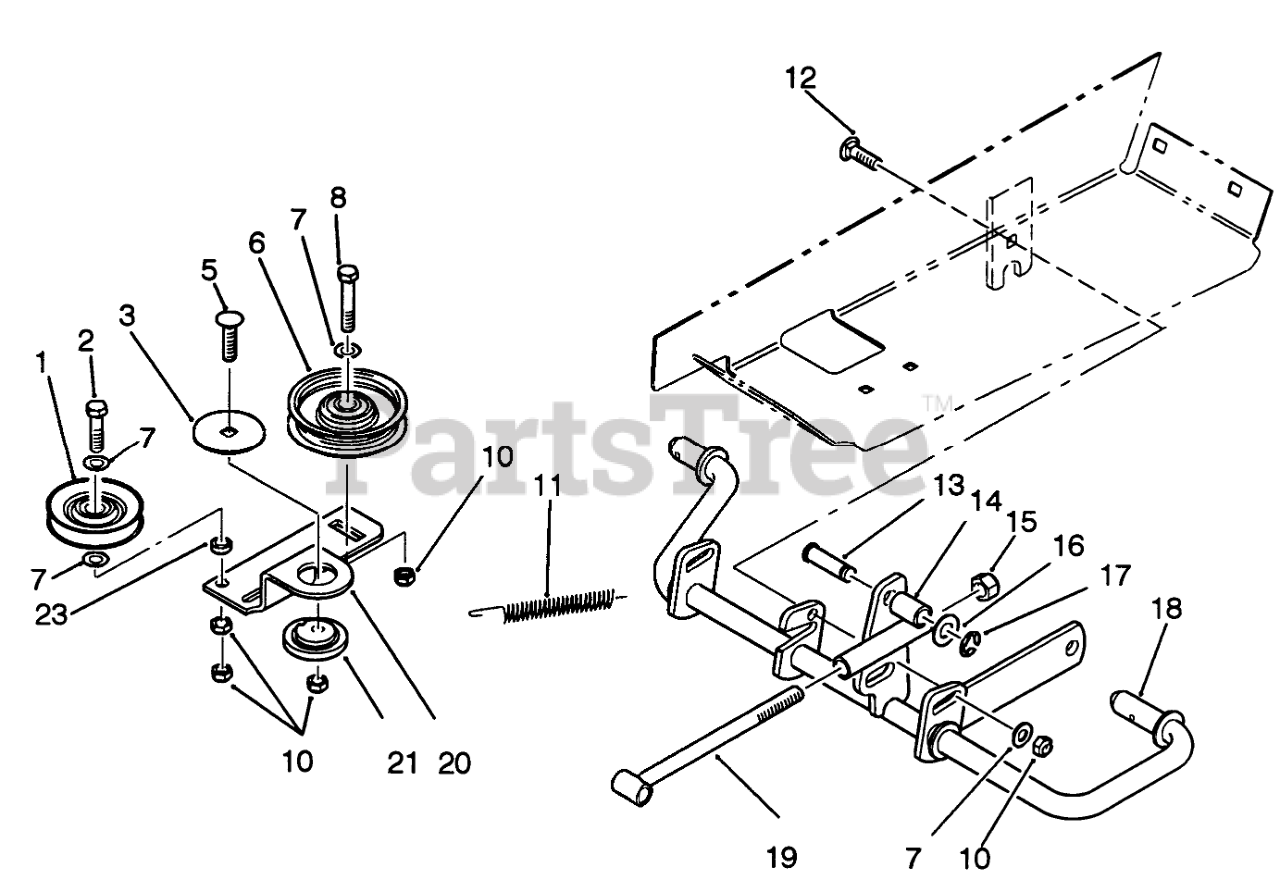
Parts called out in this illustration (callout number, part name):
1	Pulley
2	BOLT
3	WASHER-BEARING
5	Bolt
6	Idler Pulley
7	WASHER-FLAT
8	SCREW-HH
10	NUT-LOCK, NI
11	SPRING - CLUTCH
12	SCREW-CARR
15	NUT-LOCK, NI
16	WASHER-FLAT
17	RING-RETAINING, EXTERNAL
18	Shaft
20	ARM-IDLER
21	BUSHING
23	SPACER
